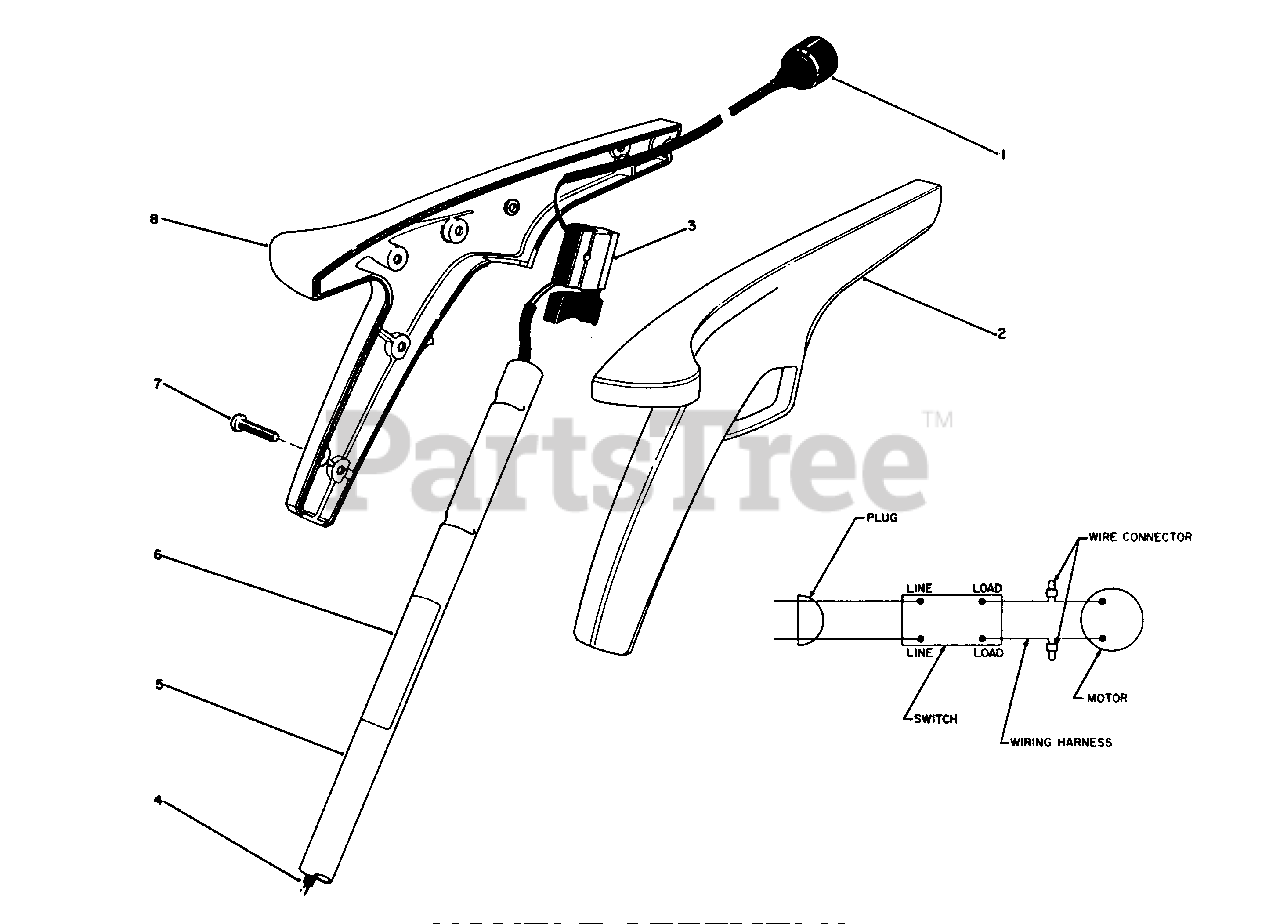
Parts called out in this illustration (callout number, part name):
1	Plug-Pigtail
2	Grip-L.H.
4	Harness-Wiring
6	Decal-Serial No.
7	Replacement Screw
8	Grip-R.H.
